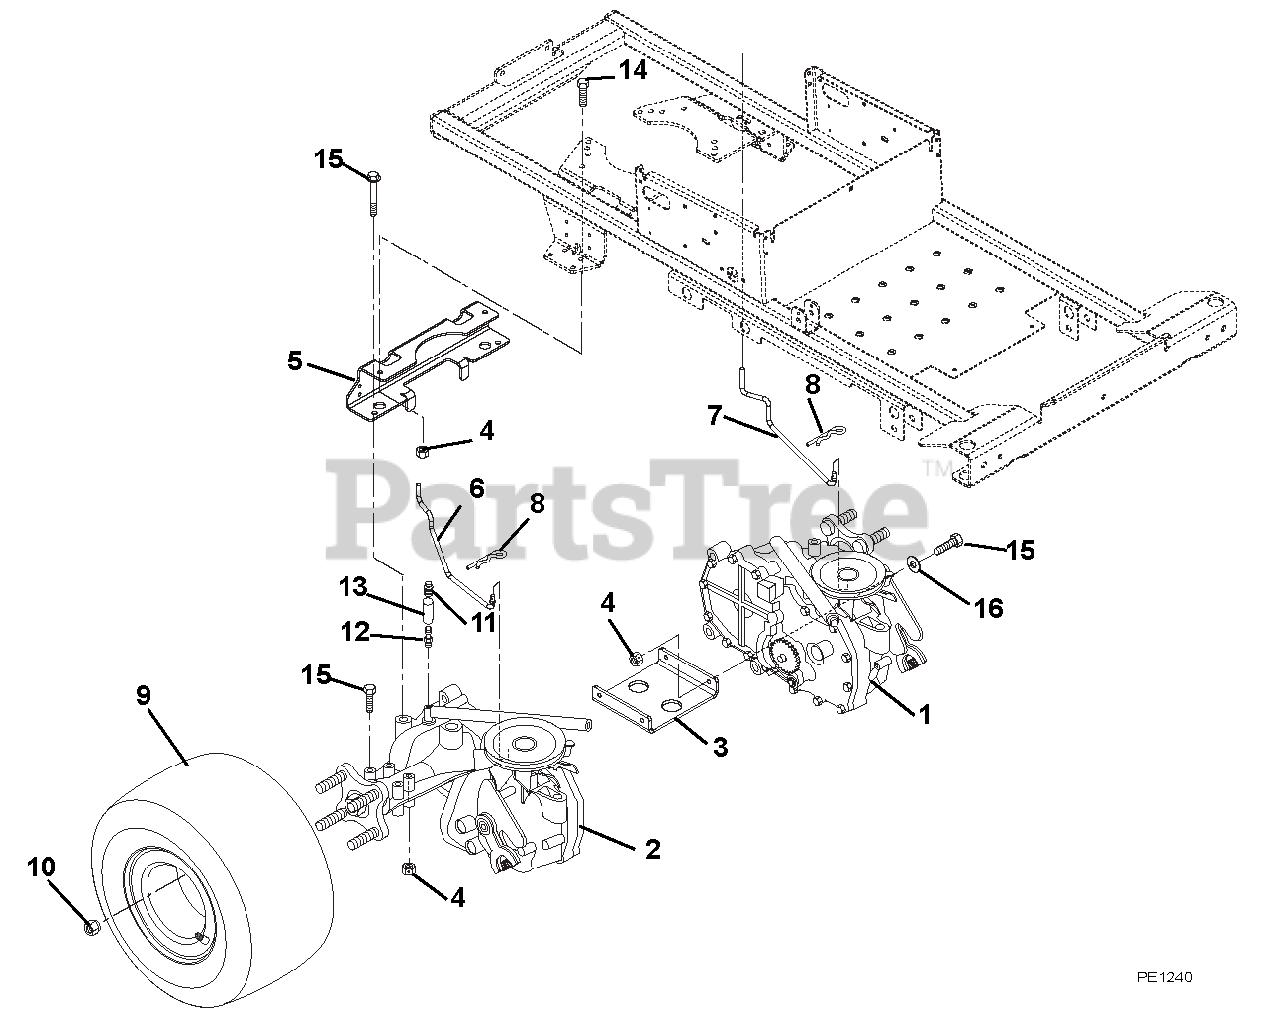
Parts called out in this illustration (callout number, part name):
1	EZT,LH TRANSAXLE
2	EZT,RH TRANSAXLE
3	SUPPORT,TRANSAXLE
4	@NUT-LK-NYL-FLG .31-18 YWZC
5	BKT,CLUTCH STOP
6	RH DUMP ROD
7	LH DUMP ROD
8	PIN-HAIR INT .08X.18X1.18 YWZC
9	ASSY-TIRE 8.5X18 2PLY
10	NUT-LUG .50-20 YWZC
11	CAP-VENT .50
12	FTG-STR .50 O-RING
13	HOSE - VENT
14	@BLT-HEX .31-18X1.00 GR5 YWZC
15	@BLT-HEX .31-18X2.75 GR5 YWZC
16	WSHR-FL-STL .328X.87X.179 YWZC
